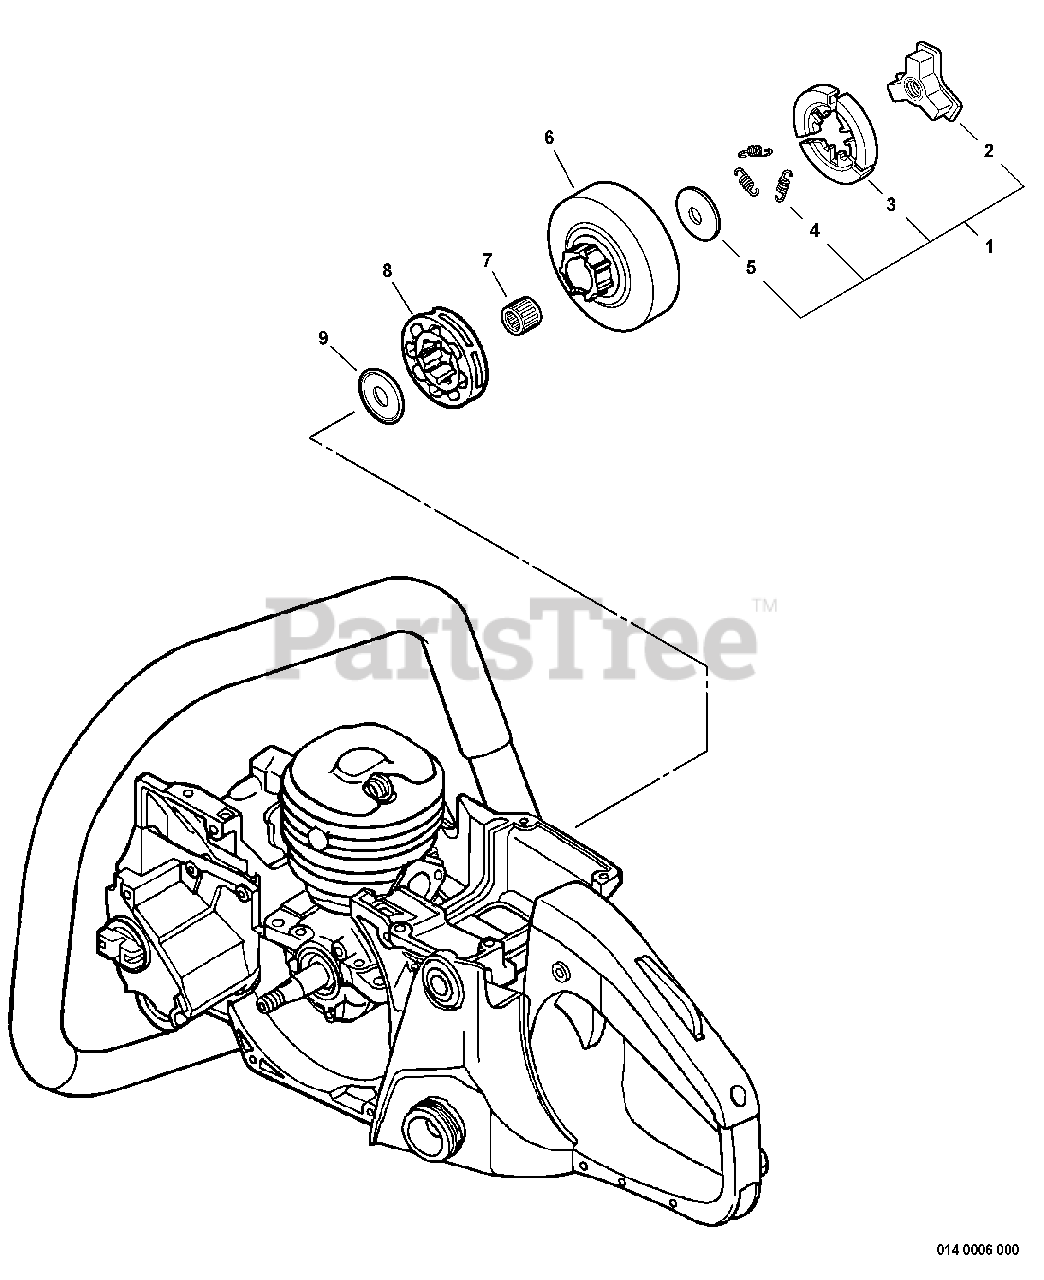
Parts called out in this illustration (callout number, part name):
1	CLUTCH ASSY
2	HUB, CLUTCH
3	SHOE SET, CLUTCH (3PCS)
4	SPRING, TENSION
5	PLATE, CLUTCH
6	DRUM, CLUTCH
7	BEARING, NEEDLE
8	SPROCKET, 0.325 RIM
9	PLATE, CLUTCH
